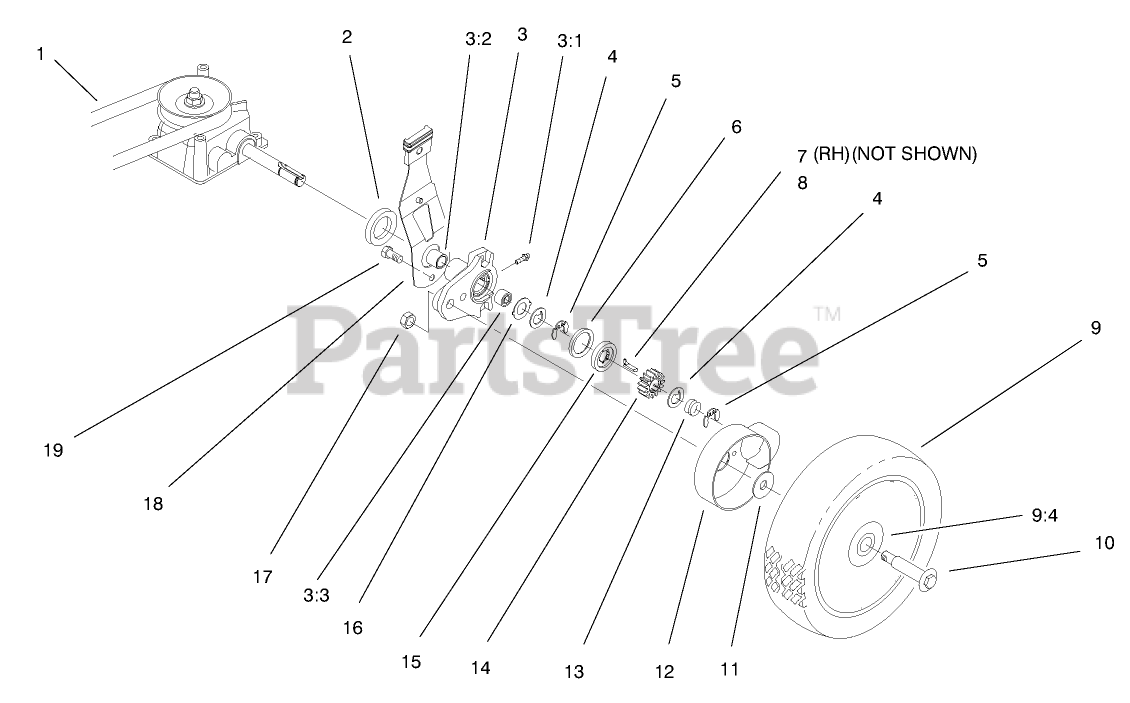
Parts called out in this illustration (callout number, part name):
1	V-BELT
2	SPACER-SHAFT, AXLE
3	REAR HEIGHT ADJUSTMENT ARM ASM
3:1	FITTING-GREASE
3:2	BUSHING
3:3	BUSHING
4	WASHER-THRUST, KEYED
5	RING-RETAINING,CLIP
6	RING-FRICTION
7	KEY-ROCKING, RH
8	KEY-ROCKING, LH
9	WHEEL ASM
9:4	BUSHING
10	BOLT-SHOULDER
11	WASHER-STEPPED
12	COVER-WHEEL
13	SPRING-COMPRESSION
14	GEAR-PINION
15	WASHER-CLUTCH
16	WASHER-ARM, PIVOT
17	NUT-JAM, LOCKING
18	REAR SPRING ARM ASM
19	SCREW-HWH
